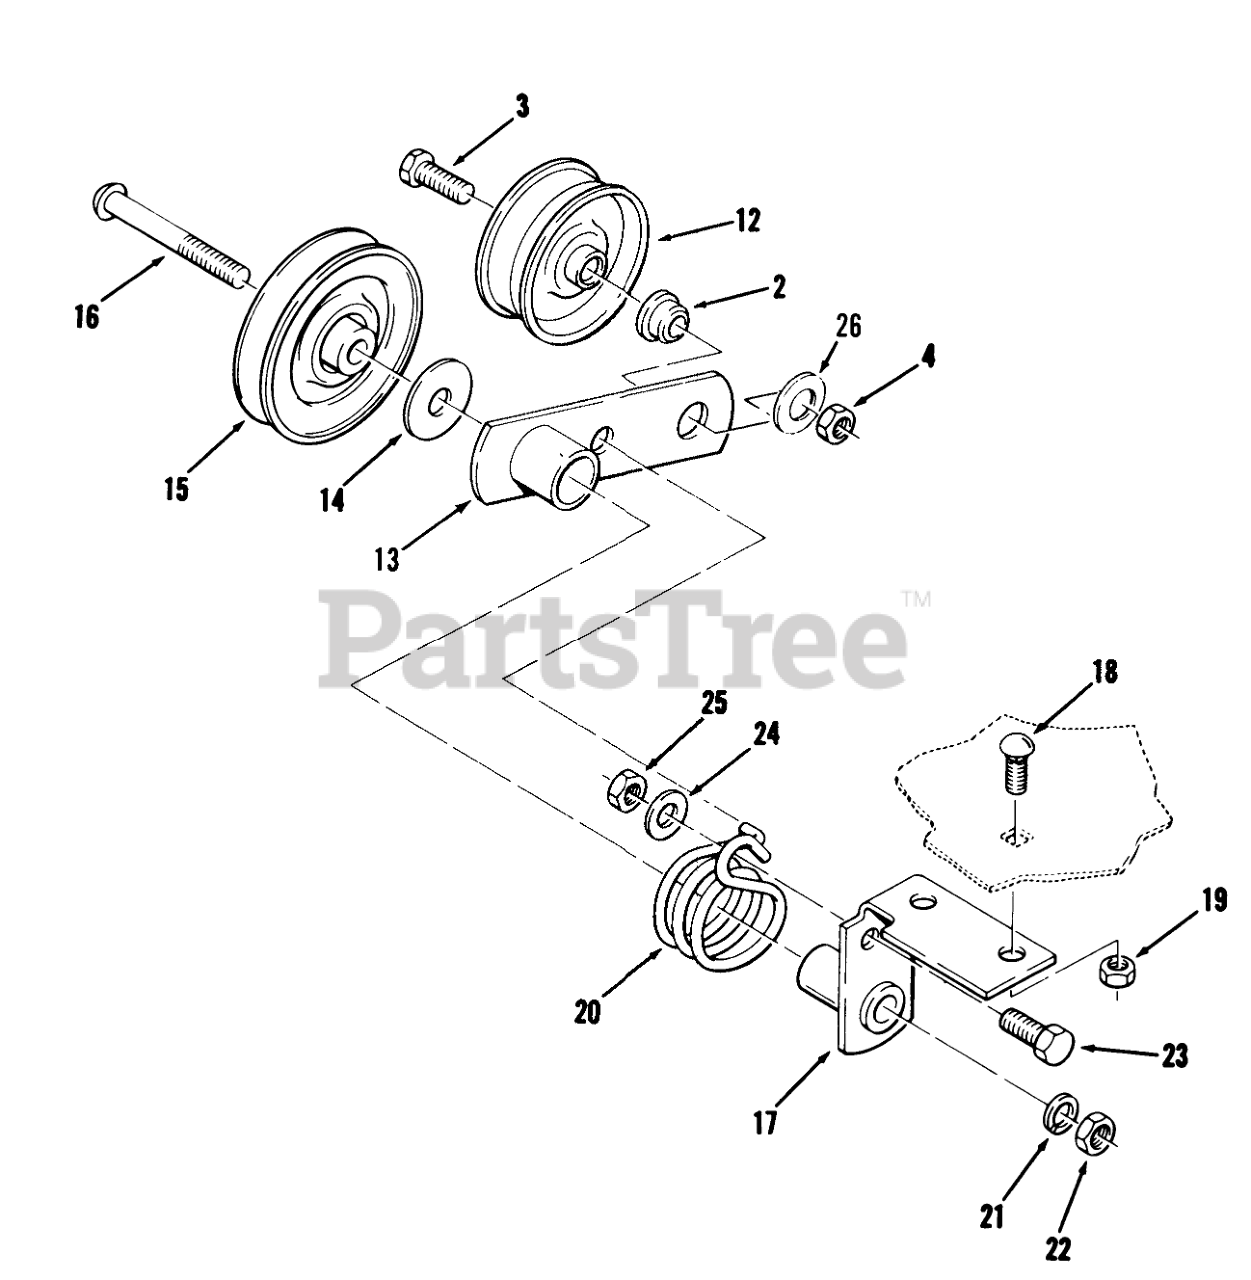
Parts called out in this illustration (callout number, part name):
2	SPACER-BRAKE LINK
3	Bolt
4	NUT
12	IDLER PULLEY
13	ASSY-IDLER ARM
14	WASHER
15	PULLEY-IDLER
16	SCREW 3/8-16X23/4
17	Idler Arm Support
18	Bolt
19	Nut
20	SPRING-TORSION
21	LOCKWASHER
22	Nut
23	Bolt
24	Washer
25	Nut
26	WASHER
